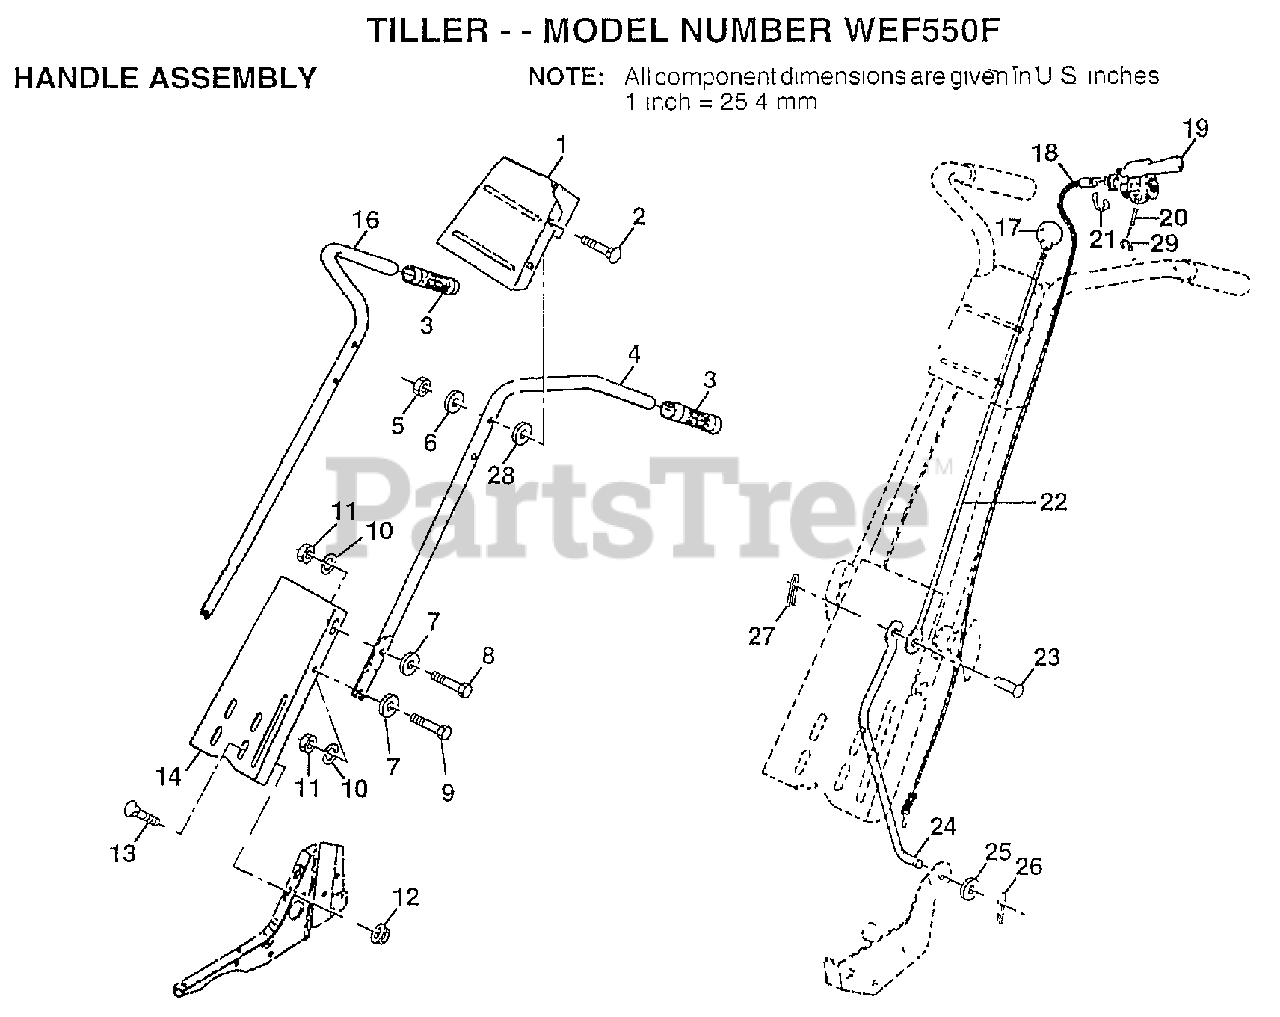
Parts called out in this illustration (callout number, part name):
1	BRACKET.HDLE.TILL
2	BOLT
4	HANDLE.LH TILLER
6	WASHER
7	WASHER
9	BOLT
10	LOCKWASHER
11	NUT.HEX.5/16-18
12	NUT
13	BOLT
14	PANEL.HANDLE.PNT.
16	"HANDLE-RH,TILLER"
17	KNOB T(3/8 HOLE)
18	CABLE CLUTCH T
19	LEVER CONTRL TINE
21	E-RING
22	ROD REVERSE TI
23	RIVET.RD.HD.DRILL
24	REVERSE ROD TI
25	WASHER
26	COTTER PIN
28	WASHER
29	RETAINER RING
